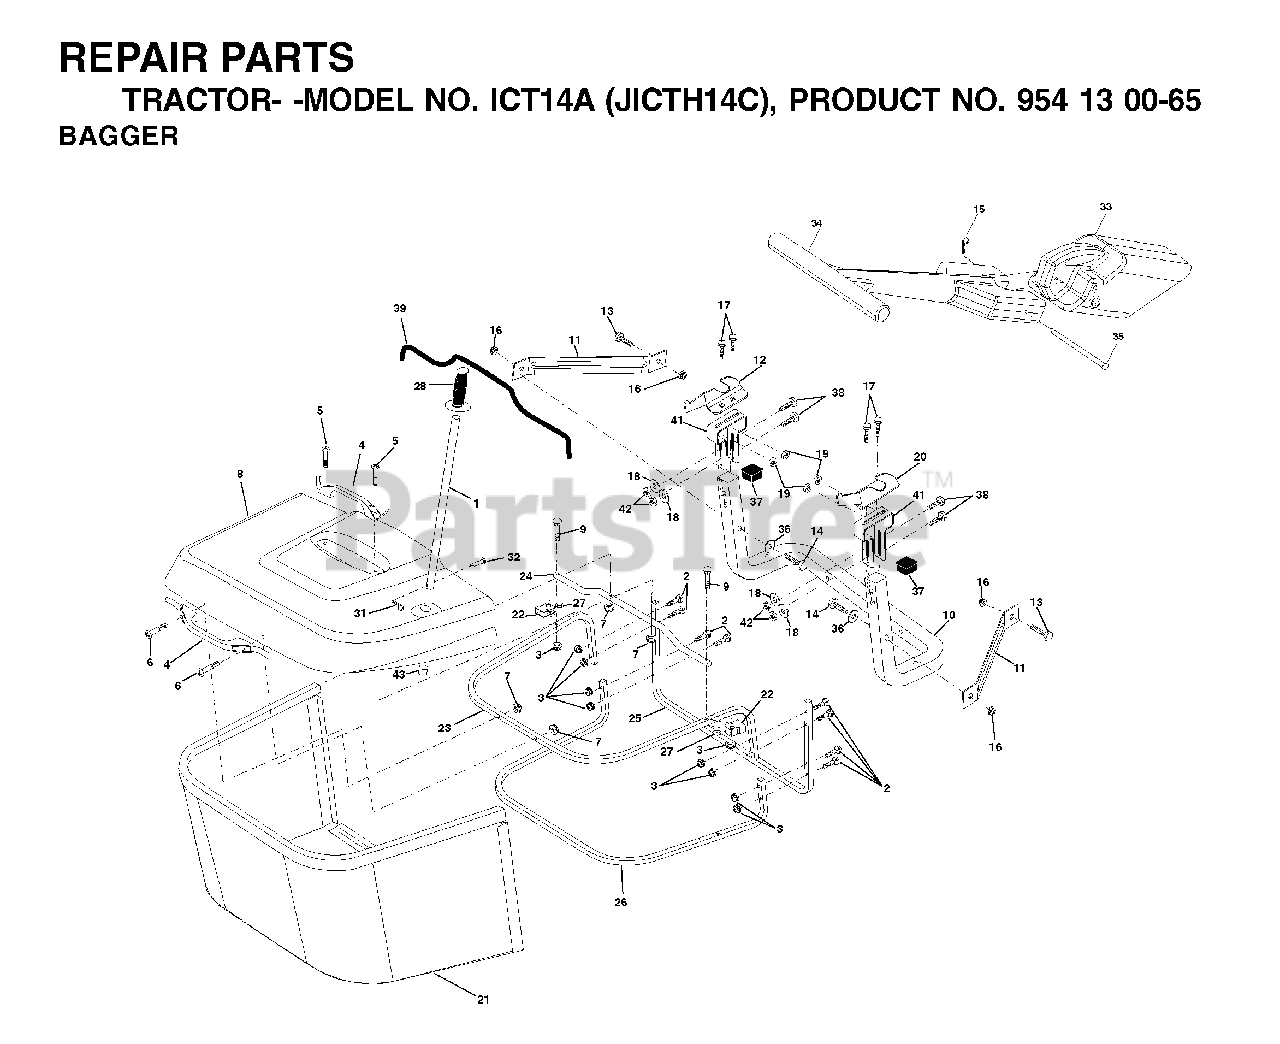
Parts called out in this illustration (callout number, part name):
1	TUBE HANDLE
3	NUT T
5	SCREW.PAN.HEAD
11	BRACKET
14	BOLT-HEX EAK
15	RETAINER-SPRNG RB
16	NUT LOCK FLG 3/8-16 UNC
17	BOLT
18	WASHER M
19	NUT LOCK HEX FLANGE 5/16-18
20	BRACKET
21	BAG
22	BRACKET
23	TUBE
24	TUBE
26	TUBE
28	GRIP.HANDLE.BLACK
31	RETAINER M
32	RIVET,DRILLED
33	PLUG
35	PIN
36	WASHER
38	BOLT.5/16-18X2.5
41	BRKT, BAGGER
42	NUT.71038.31-18.HEX.NYLOCK
43	PLUG, TUBING END
